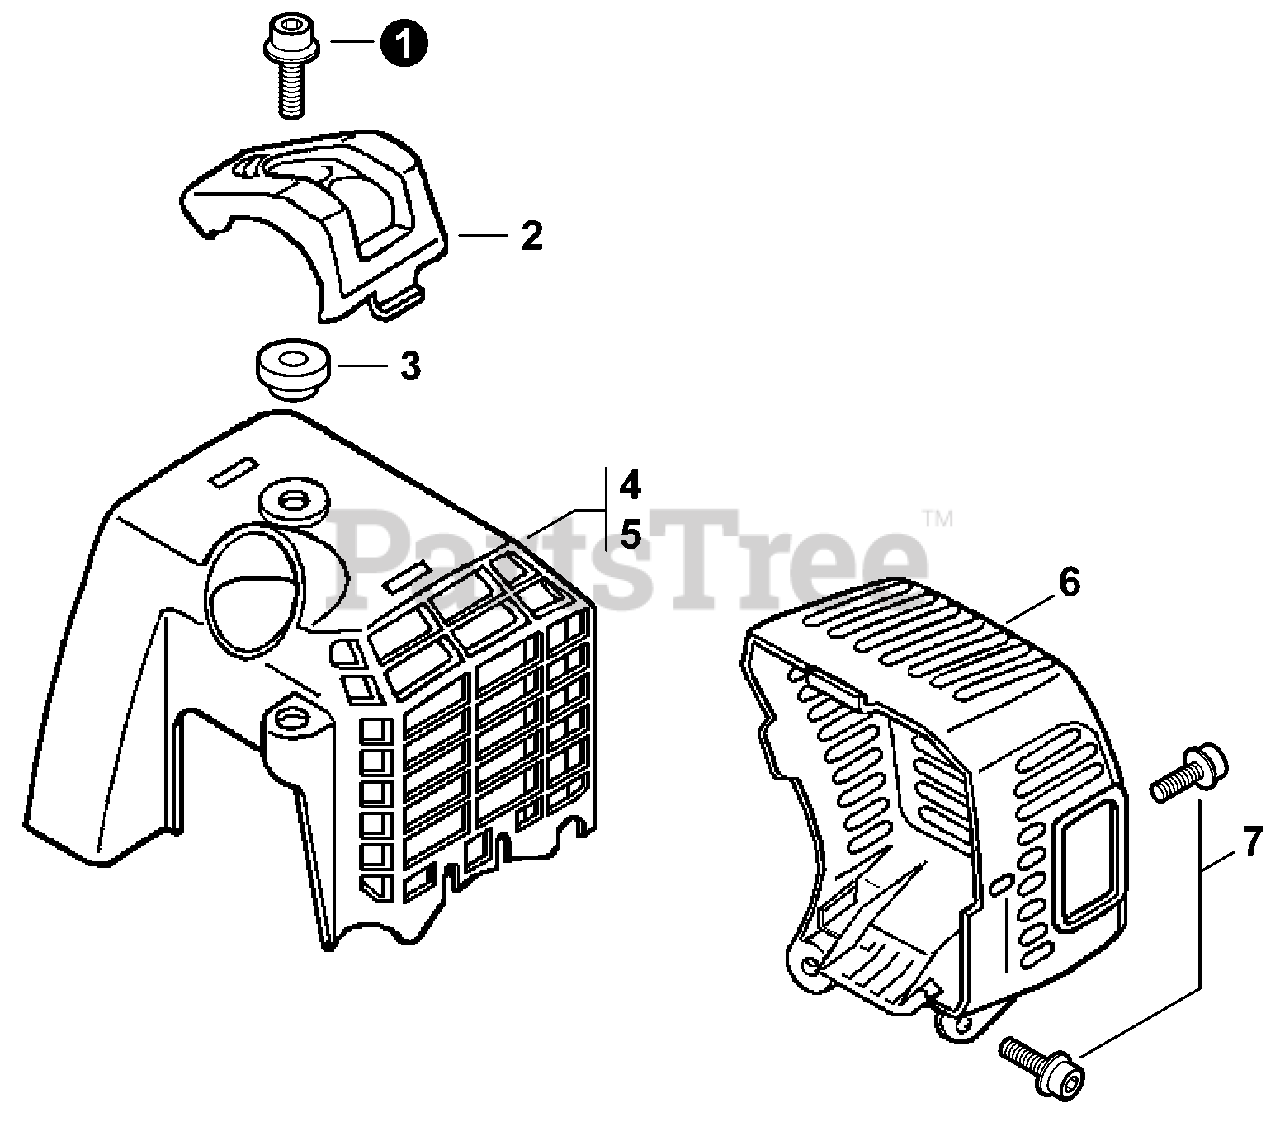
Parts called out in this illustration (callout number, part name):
1	BOLT 5×16
2	GUARD, TOP
3	COLLAR 5
4	COVER, ENGINE - GRAY
5	COVER, ENGINE - ORANGE
6	COVER, MUFFLER
7	BOLT 5×12
